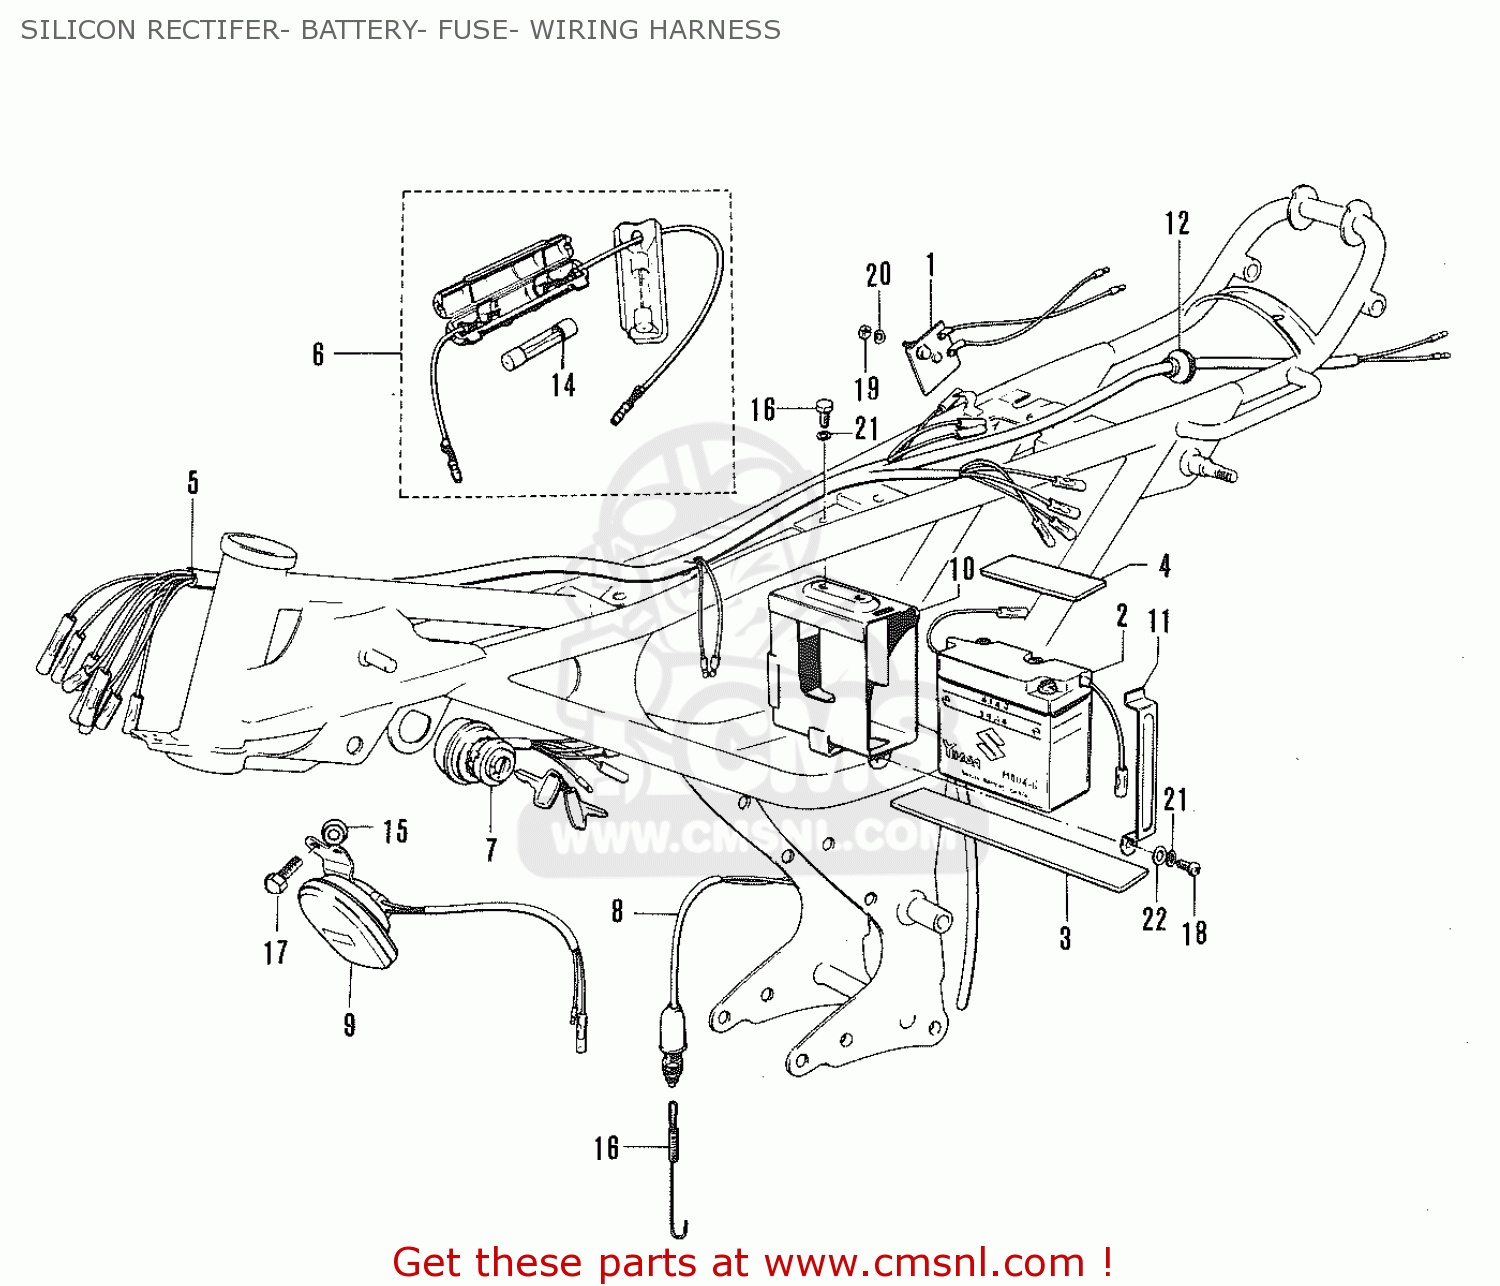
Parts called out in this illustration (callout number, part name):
1	RECTIFIER ASSEMBLY
2	BATTERY(6N4B-2A,6V4.2AH)
3	CUSHION,BATTERY
4	PROTECTOR,BATTERY
5	HARNESS,WIRING
6	BOX ASSEMBLY,FUSE
7	SWITCH ASSEMBLY,IGNITION
8	SWITCH,BRAKE LAMP
9	HORN ASSEMBLY
10	HOLDER,BATTERY
11	BRACKET,BATTERY HOLDER
12	GROMMET
13	SPRING
14	FUSE(15A)
15	WASHER
16	HEXAGON BOLT
17	BOLT
18	SCREW, CENTER SHAFT
19	NUT
20	LOCK WASHER
21	LOCK WASHER
22	WASHER
